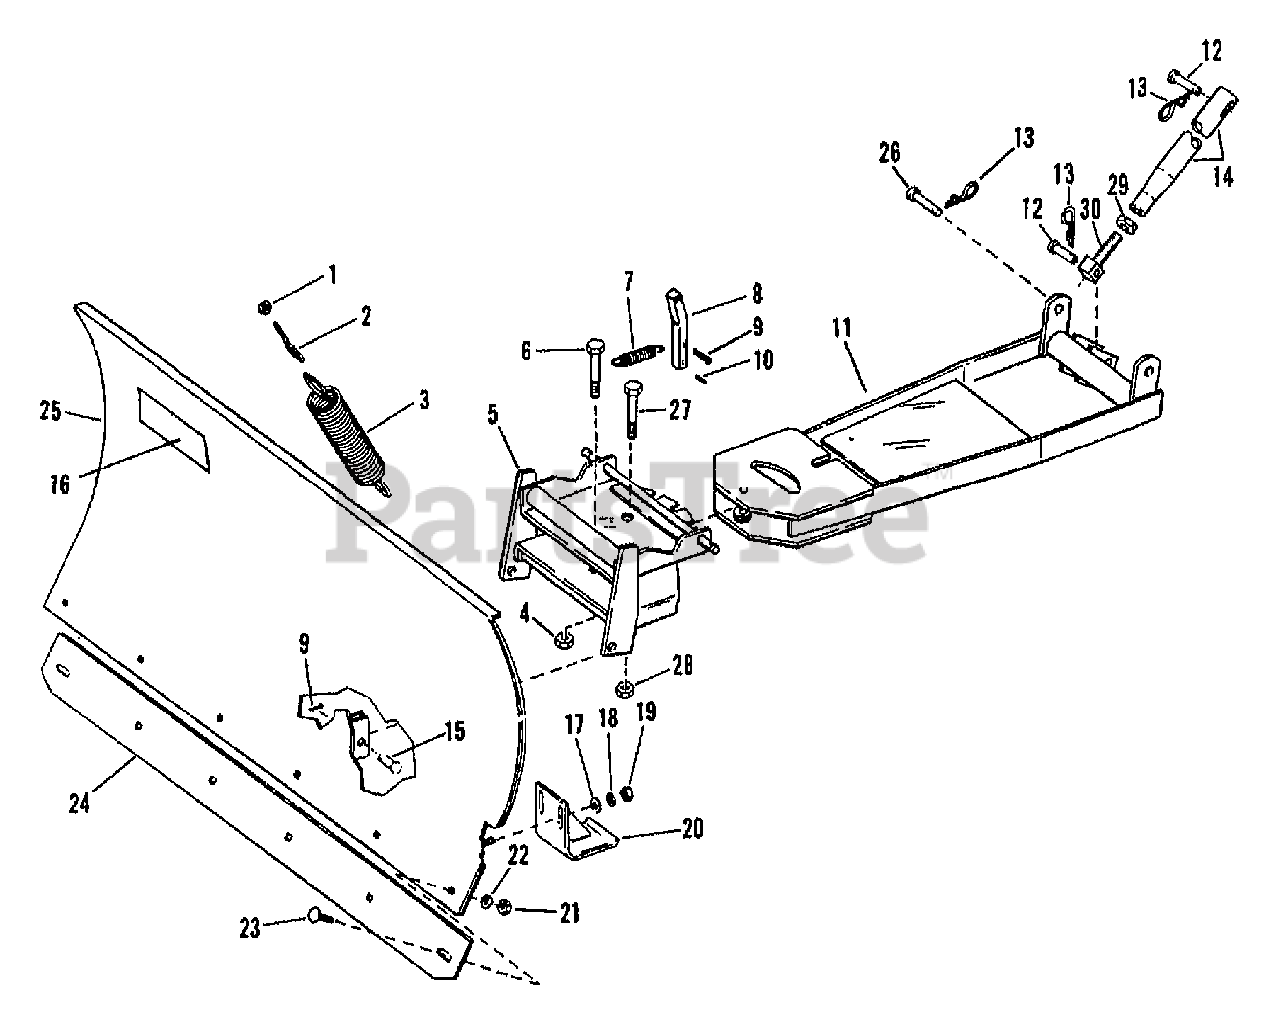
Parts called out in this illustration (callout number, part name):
1	NUT-TOP/LK 5/16-18 ZP
2	BOLT-EYE 5/16-18X2.75 ZP
4	NUT-LOCK
5	ASSM-PIVOT PLATE
6	SCR-HH 5/8-11X3.0 G5
7	SPRING
8	PIN-LATCH
9	PIN-COTTER .125 X .75 ZP
10	PIN-DRIVE .125X1.0
12	PIN-CLEVIS .5X2.25
13	PIN-HITCH .125X2.56 ZP
15	PIN-CLEVIS .5X1.06 ZP
16	DECAL-LOGO
17	WASHER-FLAT 3/8 SAE
18	WASHER-LK .375 @ DEPL
19	NUT-HEX 3/8-16 ZP
20	SHOE-SKID
21	NUT-HEX 5/16-18 ZP
22	WASHER-LK .312 ZP
23	SCR-CARR 5/16-18X1.0 G2 ZP
24	BLADE-SCRAPER
26	PIN-CLEVIS .625 X 1.38
27	SCR-HH 3/8-16X2.75 G5 ZP
28	NUT-LOCK 3/8-16
29	NUT-HEX
30	ADJ-LIFT LINK
